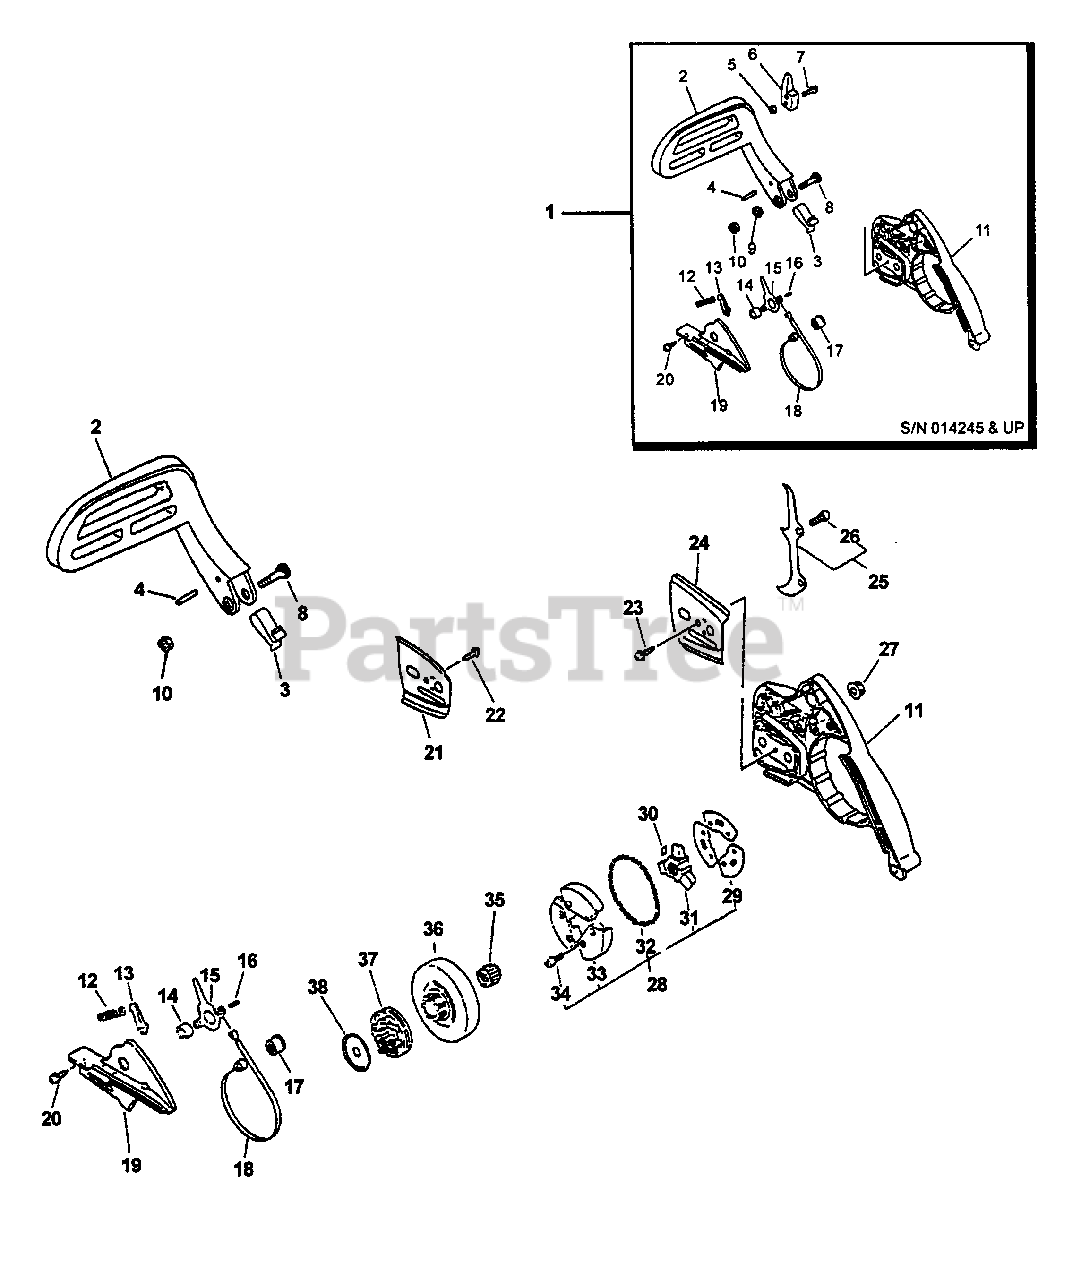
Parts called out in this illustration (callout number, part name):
1	CHAIN BRAKE ASSY
2	LEVER ASSY, BRAKE
2	BRAKE LEVER ASSY
3	SPRING
4	PIN 3×24
5	NUT M4
6	WEIGHT, BRAKE
7	SCREW 4×18
8	SCREW
8	SCREW 5×30
9	COLLAR 5.3×10×13×L5
10	NUT
10	NUT, LOCK M5
11	GUARD, SPROCKET
12	SPRING, COMPRESSION
13	STOPPER, BRAKE
14	WASHER 5.2×12×14
15	LEVER, BRAKE
16	PIN, SPRING 4×8.8
17	ADJUSTER, BRAKE
18	BAND, BRAKE
19	COVER, BRAKE
20	SCREW 4×10
21	PLATE, GUIDE - INNER
22	SCREW 4×6
23	SCREW 3×6
24	PLATE, GUIDE
25	SPIKE KIT, BUMPER
26	BOLT 5×12
27	NUT, FLANGE M8×1.25
28	CLUTCH ASSY
29	PLATE, CLUTCH
31	HUB, CLUTCH
32	SPRING, CLUTCH
33	SHOE SET, CLUTCH (3PCS)
34	BOLT 4×6
35	BEARING, NEEDLE
36	DRUM, CLUTCH
37	SPROCKET, 0.325 RIM
38	PLATE, CLUTCH
